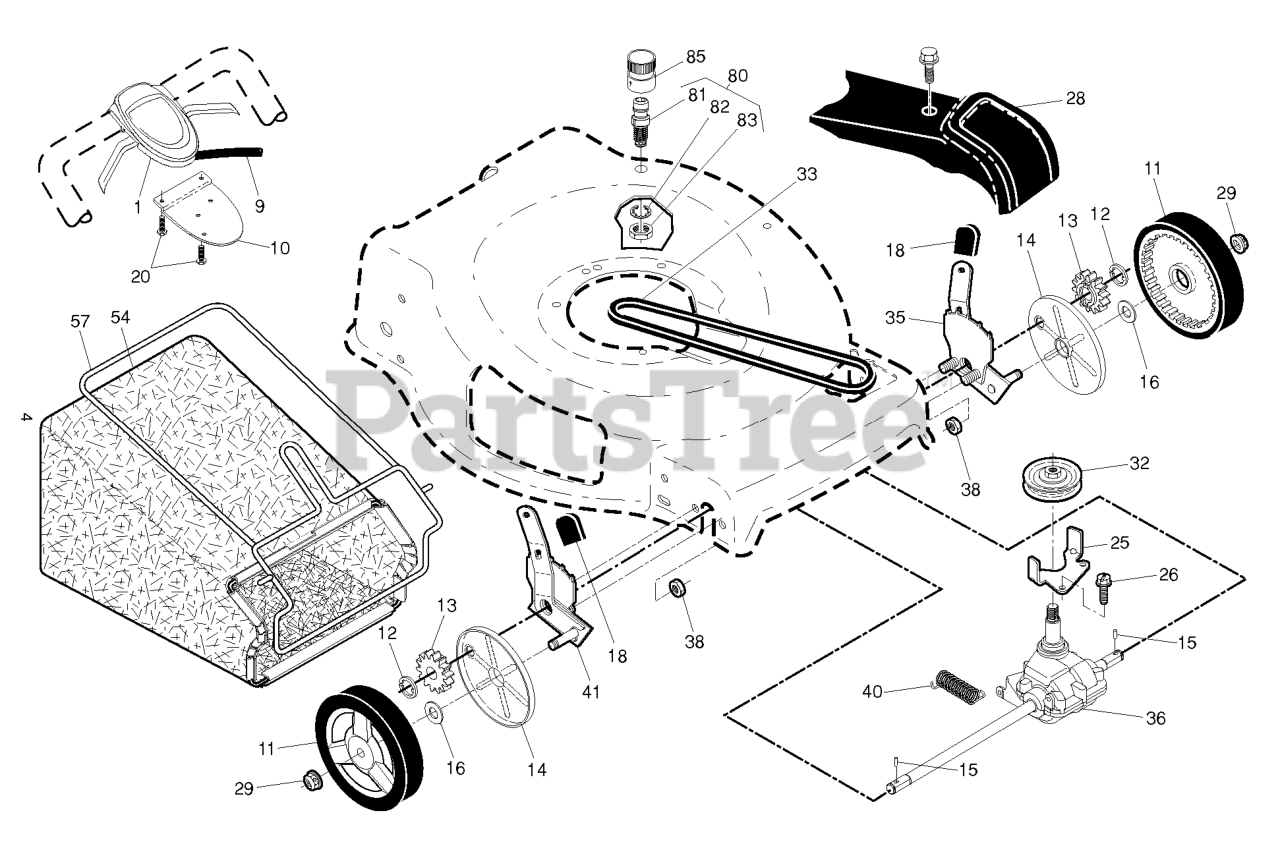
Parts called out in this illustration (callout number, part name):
1	CONTROL.AW2.22+FG.GEN.BS.BK/BK
9	CABLE.CONTROL.22FGD.GEN2
10	BRACKET.DRIVE.CONTR.GEN2.BLACK
11	WHEEL.8X1.75.H3SPK.RAD3.GY.BU3
12	E-RING 7/16 RE
13	PINION.14.TEETH.FGD
14	COVER.DUST.WHEEL.INNER.WALK
15	PAWL, DRIVE
16	WASHER FLUT
18	SELECTOR KNOB
20	SCREW, PHILLIPS HEAD 10 X 5/8
25	BRACKET.BELT.GUIDE.22+FGD.BZP
27	SCREW, HEX HD TAPPING #10-24 1
28	COVER.DR.22.MB LABEL HUSQ E/F
29	NUT.HEX.FLANGE.3/8-16.LO(3 2)
32	RP PULLEY.DRIVE.EZ/VAR.SCREWON
33	BELT.DRIVE.FWD.
35	ADJUSTER.ASM.22+FGD.LF /AWD LT
36	RP.TRANSMISSION.22+.FWGD.SS
38	NUT.FLANGE.1-4-20-SERR
41	ADJUSTER.ASM.22+FGD.RF /AWD RT
54	GBAG.A3610247T.SILV.HUSWT.BLUE
57	FRAME.GBAG.22+.BLK
80	KIT.WASH-OUT.PORT.ZINC.WALK
81	WASHOUT.PORT.ZINC.RGD.22+
82	WASHER.LOCK.INTERNAL.TOOTH
83	LOCKNUT.HEX.WITH.O-RING
84	COUPLING.QUICK CONNECT
